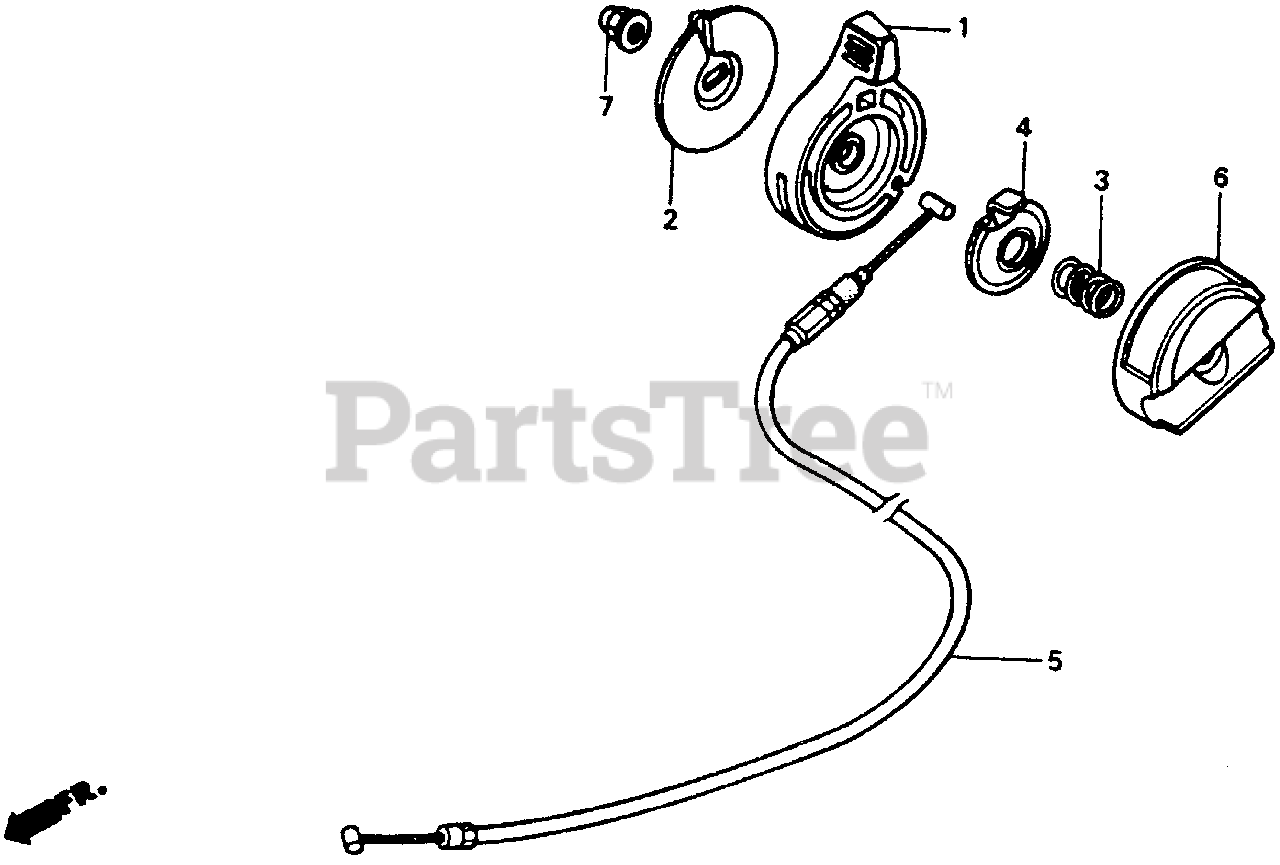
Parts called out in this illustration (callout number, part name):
1	LEVER, THROTTLE
2	PLATE, THROTTLE LEVER
3	SPRING, THROTTLE LEVER
4	SEAT, SPRING
5	CABLE, THROTTLE
6	COVER, CONTROL
7	NUT, CAP (6MM)
7	NUT, FLANGE (6MM)
